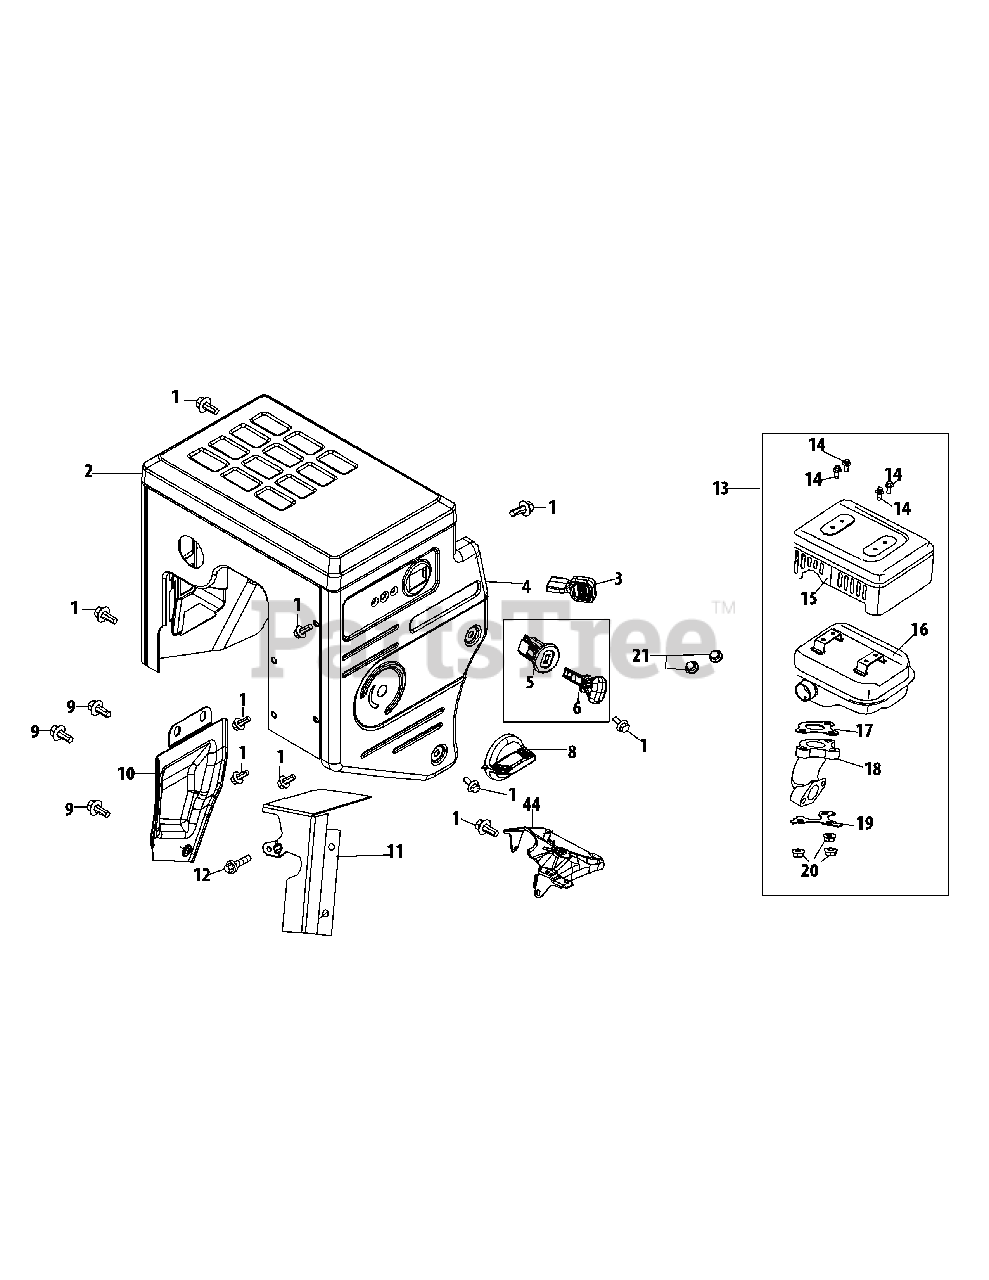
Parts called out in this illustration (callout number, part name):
1	Bolt M6×12
2	Muffler Shield
3	Throttle Control Knob
4	Control Panel
5	Engine Switch Base
6	Key
8	Choke Knob
9	Bolt M6×10
10	Exhaust Pipe Shield
11	Carb Isolator Bracket
12	Bolt M6×16
13	Muffler Assembly
14	Bolt
15	Muffler Guard
16	Muffler Body
17	Gasket, Muffler
18	Exhaust Pipe
19	Gasket
20	Nut M8
44	Throttle Bracket
